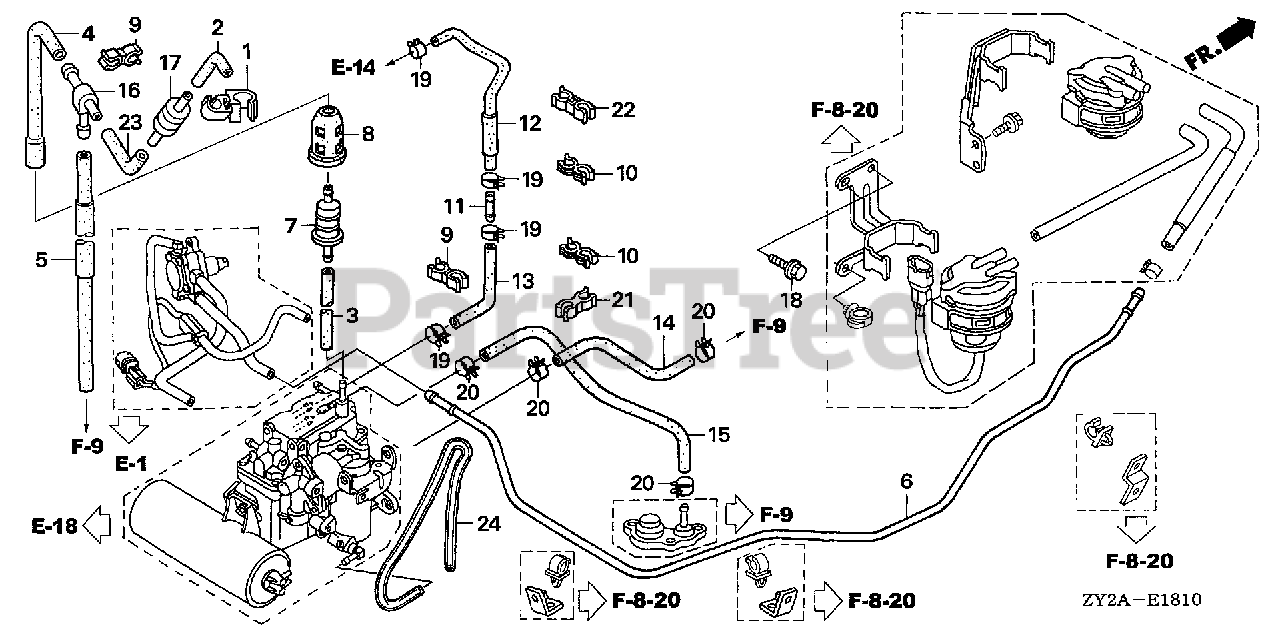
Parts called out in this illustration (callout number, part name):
1	CLAMP, CHECK VALVE
2	TUBE, CHECK VALVE
3	TUBE A, AIR VENT
4	TUBE B, AIR VENT
5	TUBE, AIR VENT
6	PIPE, FUEL
7	FILTER, FUEL PUMP
8	SUSPENSION, STRAINER
9	CLAMP, HOSE
10	CLIP, TUBE
11	JOINT, FUEL RETURN
12	HOSE A, PRESSURE REGULATOR RETURN
13	HOSE B, PRESSURE REGULATOR RETURN
14	TUBE, WATER INLET
15	TUBE, WATER OUTLET
17	VALVE, CHECK
18	BOLT, FLANGE (6X10)
19	CLAMP, TUBE (D10.7)
20	CLAMP, TUBE (D10.5)
21	CLIP, WIRE
22	CLAMP, FUEL TUBE
23	BULK HOSE, FUEL (3.5X3000) (3.5X55)
24	BULK HOSE, VINYL (3.5X6.5X8000) (3.5X6.5X600)
